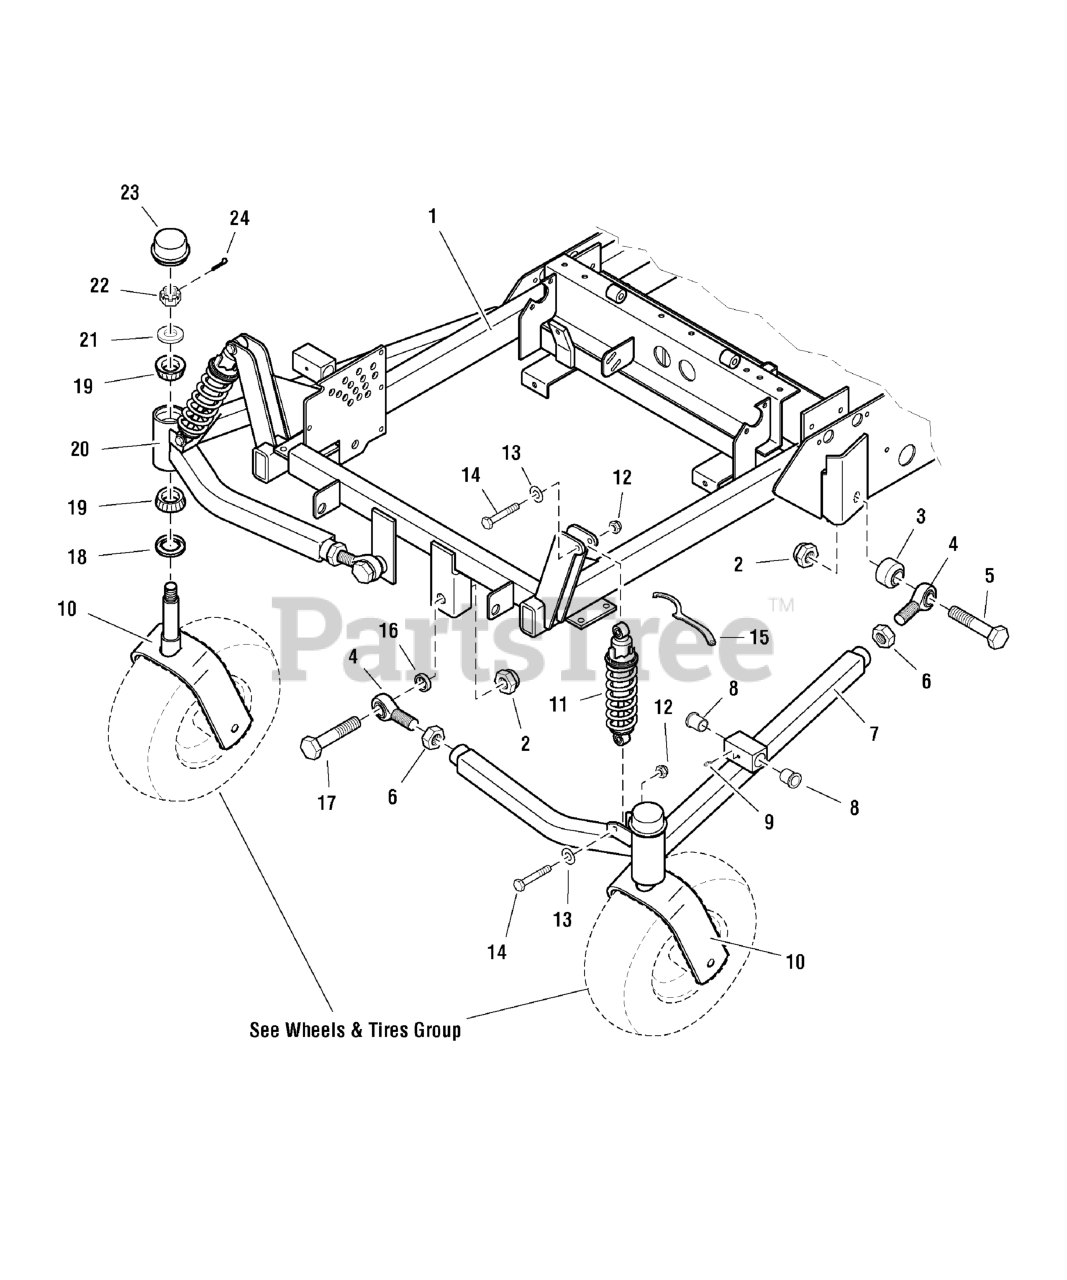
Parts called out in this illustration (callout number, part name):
1	MAIN FRAME
2	NUT, 3/4-16 Hex Nylon Lock
3	SPACER, .75 x 1.50 x 1.00
4	BALL JOINT, 3/4-16 Male
5	BOLT, 3/4-16 x 3-1/2
6	NUT, 3/4-16 Hex Jam
7	SUSPENSION ARM ASSEMBLY - LH, Complete
8	BUSHING, Flange
9	GREASE FITTING
10	CASTER TIRE MOUNT
11	SHOCK & SPRING ASSEMBLY
12	NUT, 3/8-16 HEX NYLON LOCK
13	WASHER, 3/8 SAE
14	BOLT, 3/8-16 X 2, GD5, CZ
15	WRENCH, SPANNER, CZ
16	SPACER, .75 x 1.00 x .25
17	BOLT, 3/4-16 x 3
18	SEAL, GREASE
19	BEARING, Tapered Roller
20	SUSPENSION ARM ASSEMBLY - RH, Complete
21	WASHER, 3/4 SAE
22	NUT, 3/4-16 Hex Slotted
23	CAP
24	PIN, COTTER, 1/8 X 1-1/4
